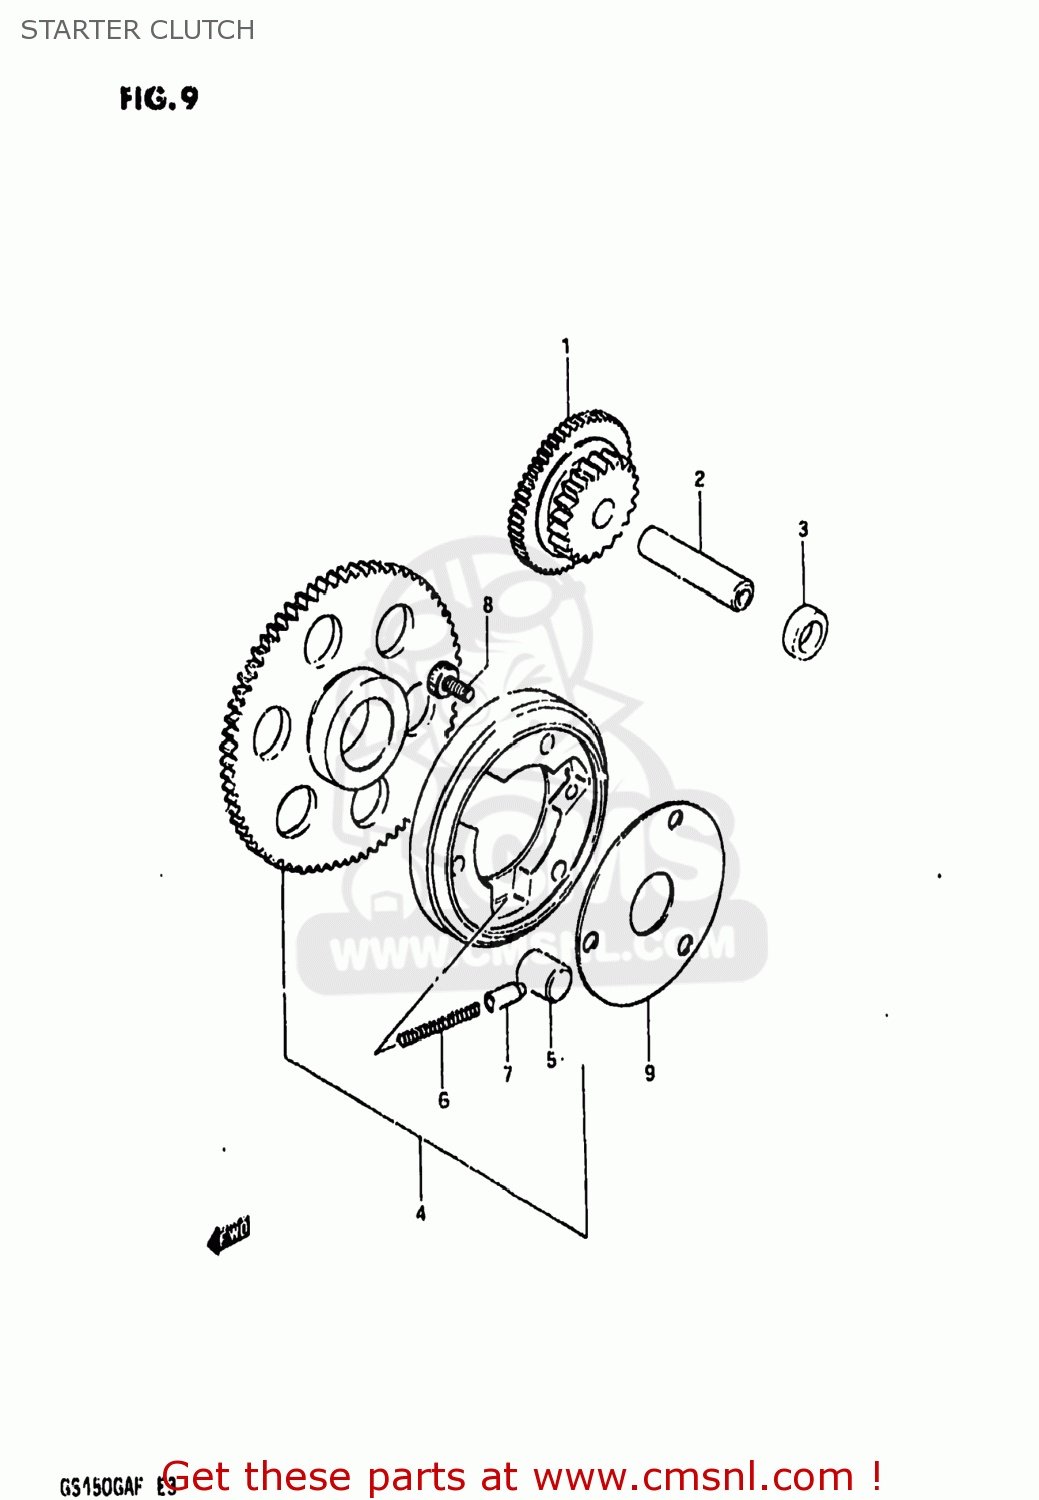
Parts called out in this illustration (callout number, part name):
1	GEAR,STARTER IDLE
2	PIN(7.4X13X56)
3	SPACER
4	CLUTCH SET,STARTER
5	ROLLER(15X13)
6	SPRING
7	PIECE,PUSH
8	BOLT
9	SHIM,STARTER CLUTCH HUB
